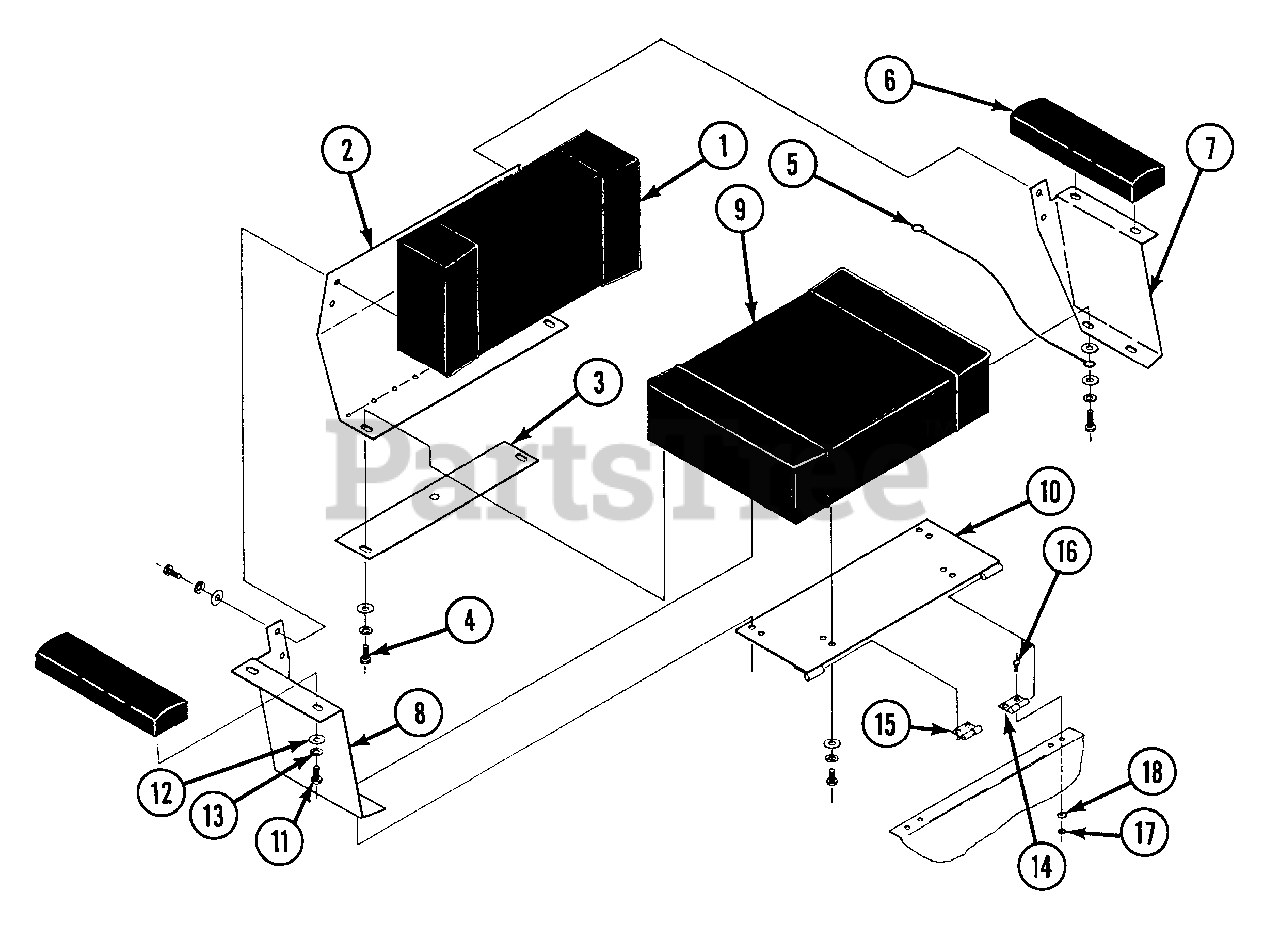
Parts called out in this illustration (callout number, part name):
1	BACK CUSHION ASSEMBLY
2	BACK REST COVER
3	ACTUATOR WELDMENT, SEAT SWITCH
4	CAPSCREW, HX HD: 5/16-18 X 1 GR 5
5	CABLE ASSEMBLY, SEAT
6	ARM CUSHION ASSEMBLY
7	ARM SUPPORT LEFT
8	ARM SUPPORT RIGHT
9	SEAT CUSHION ASSEMBLY
10	SEAT HINGE WELDMENT
11	CAPSCREW, HX HD: 5/16-18 X 3/4 GR 5
12	FLAT WASHER: 5/16
13	LOCKWASHER, SPLT SPRNG: 5/16
14	SEAT HINGE, LH
15	SEAT HINGE, RH
16	CAPSCREW, HX HD: 1/4-20 X 5/8, GR 5
17	LOCKNUT, NYLOCK: 1/4-20
18	FLAT WASHER: 1/4
